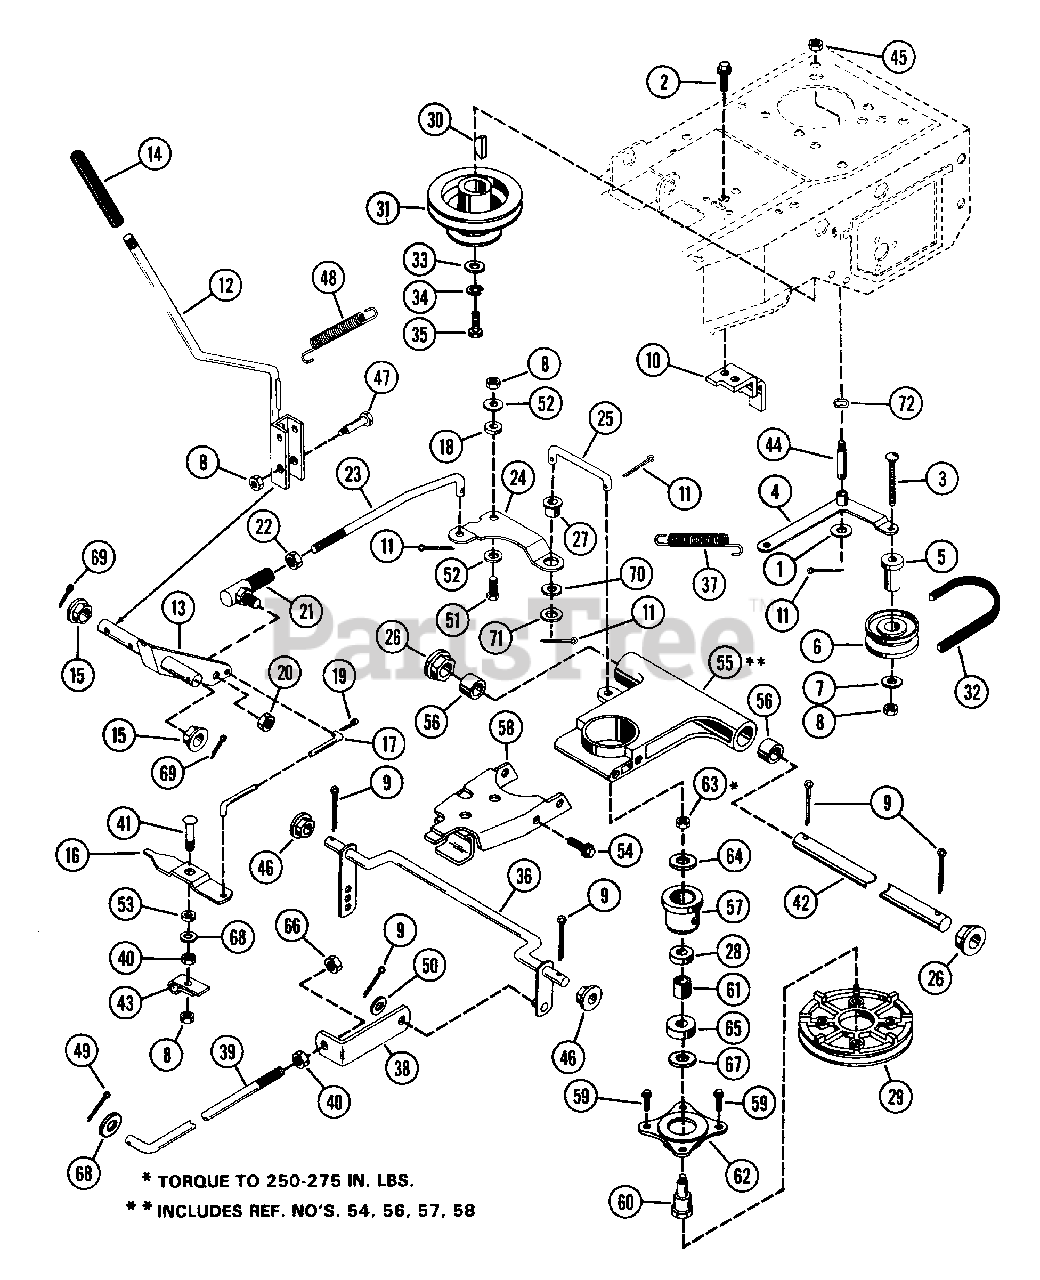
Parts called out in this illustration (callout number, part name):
1	WSHR-FL-STL .505X.880X.072 PL
2	BLT-SERHFWH .31-18X.50 PL
3	BLT-RDHDSQNK .31-18X1.25 SHTPL
4	IDLER ARM
5	SPACER -SHLD .344X.500X.469
6	IDLER
7	WSHR-FL-STL .38X.875X.083 PL
8	NUT-LK .312-18 GR A PL
9	PIN-COTR .12X1.0 PL
10	NEUTRAL STOP
11	PIN-COTR .09X.75 PL
12	SHIFT LEVER
13	SHIFT ARM
14	GRIP
15	FLANGE BUSHING
16	INDICATOR
17	INDICATOR ROD
18	SPACER BUSHING .5 X .32 X .21
19	PIN-COTR .06X.50
20	NUT-LK-CTR .312-24 PL
21	SNAP IN BALL JOINT
22	NUT-HEX .312-24 PL
23	SHIFT ROD
24	BELL CRANK
25	SHIFT LINK
26	FLANGE BUSHING
27	BSHG-FLG .372X.500X.312X.625NY
28	BRG-BALL .625X1.375X.44
30	KEY-STR .25X2.0X.25
31	ENGINE SHEAVE
32	V-BELT, 3L-RAW EDGE
33	WSHR-FL-STL .505X1.140X.250
34	WSHR-LK .375X.115 HVY PL
35	BLT-HEX .38-24X1.25 BLKO GR5
36	CLUTCH SHAFT
37	SG-TENS .062X.72X6.65 WLD 7
38	CLUTCH BRACKET
39	ROD, CLUTCH
40	NUT-HEX .312-18
41	BLT-RDHDSQNK .31-18X1.0 SHT PL
42	TRANSFER SHAFT
44	SHOULDER STUD
45	NUT-LK-CTR .375-16 GR A PL
46	FLANGE BUSHING
47	SHOULDER BOLT .436 X .912
48	SG-TENS .092X.69X1.75 WLD 54
49	PIN-COTR .12X.75 PL
50	WSHR-FL-STL .520X.810X.033
51	BLT-HEX .31-18X.75 PL GR2
52	WSHR-FL-STL .344X1.125X.063PL
53	SPACER BUSHING .5 X .32 X .163
54	BLT-SCRHFWH .25-20X.62 PL
55	CARRIER ASSEMBLY
56	BSHG-SLV .625X.750X.500 BR
57	BEARING HOUSING
58	CARRIER YOKE
59	BLT-SERHFWH .31-18X.50 PL
60	SPINDLE BOLT
61	BSHG-SLV .634X1.000X.465
62	DISC ADAPTER
63	NUT-LK-CTR .50-20 PL
64	WSHR-HDND-STL-THR.515X.97X.062
65	BRG-BALL .750X1.781X.61
66	NUT-LK-NYL.312-18 PL
67	WSHR-HDND-THRST .758X1.23X.031
68	WSHR-FL-STL .323X.625X.062 PL
69	PIN-COTR .09X1.0 PL
70	WSHR-FL-STL .531X1.250X.100 PL
71	WSHR-FL-STL .380X.626X.033
72	WAVE WASHER .531X.781X.125FH
